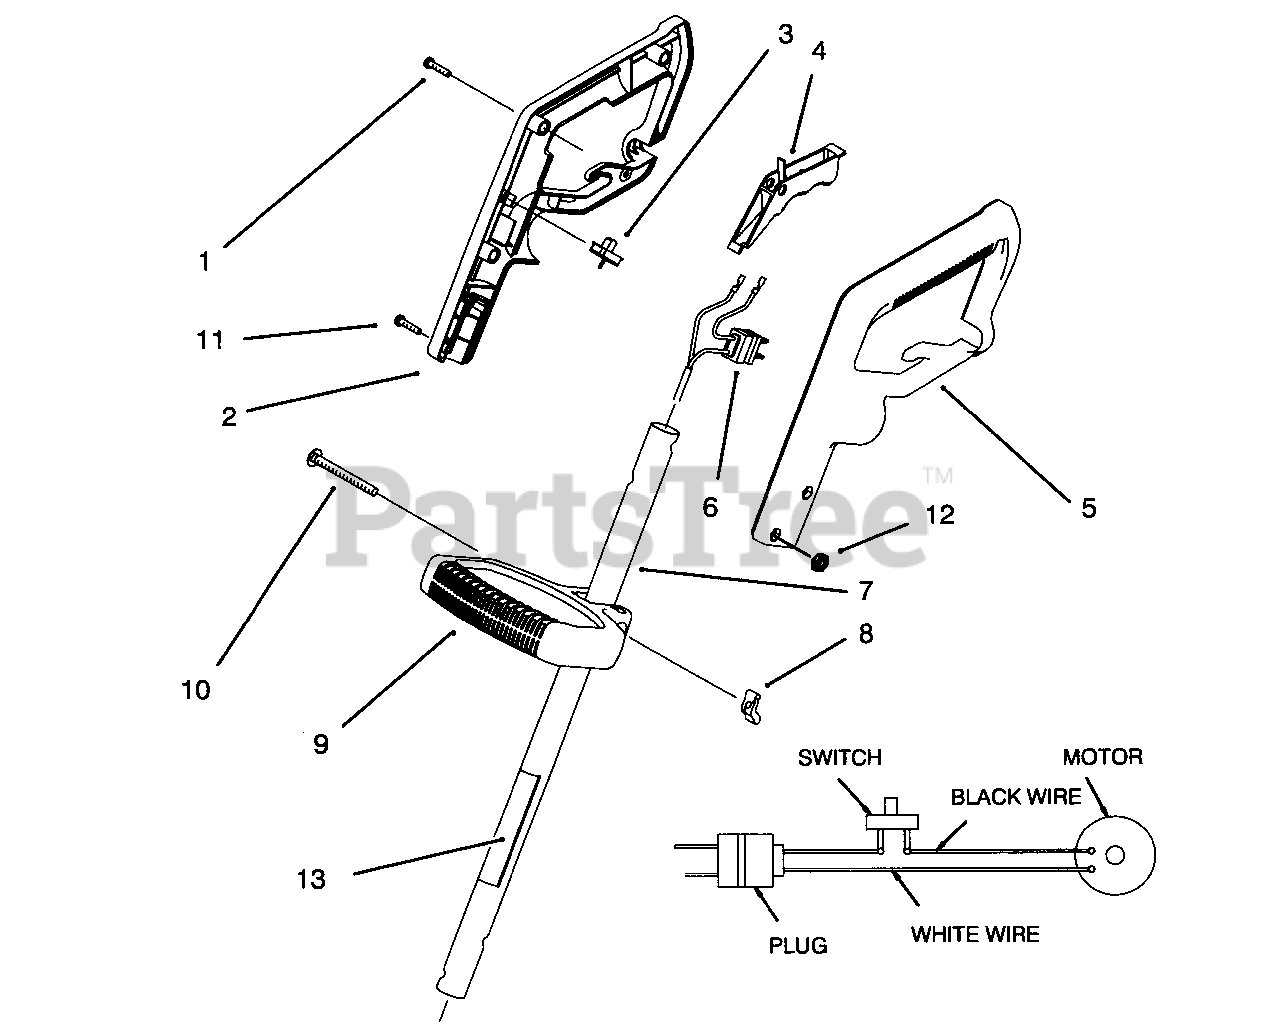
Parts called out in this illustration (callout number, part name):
1	Screw-Pan Hd Tapping
2	Grip-Hand R.H.
3	Switch-Single Speed
5	Grip-Hand L.H.
6	Harness-Wire
7	Tube Assembly (Incl. Ref. #13)
9	Handle-Mid
10	Screw-Carriage
11	Screw-Pan Hd.
12	Nut-Lock
13	Decal-Safety
